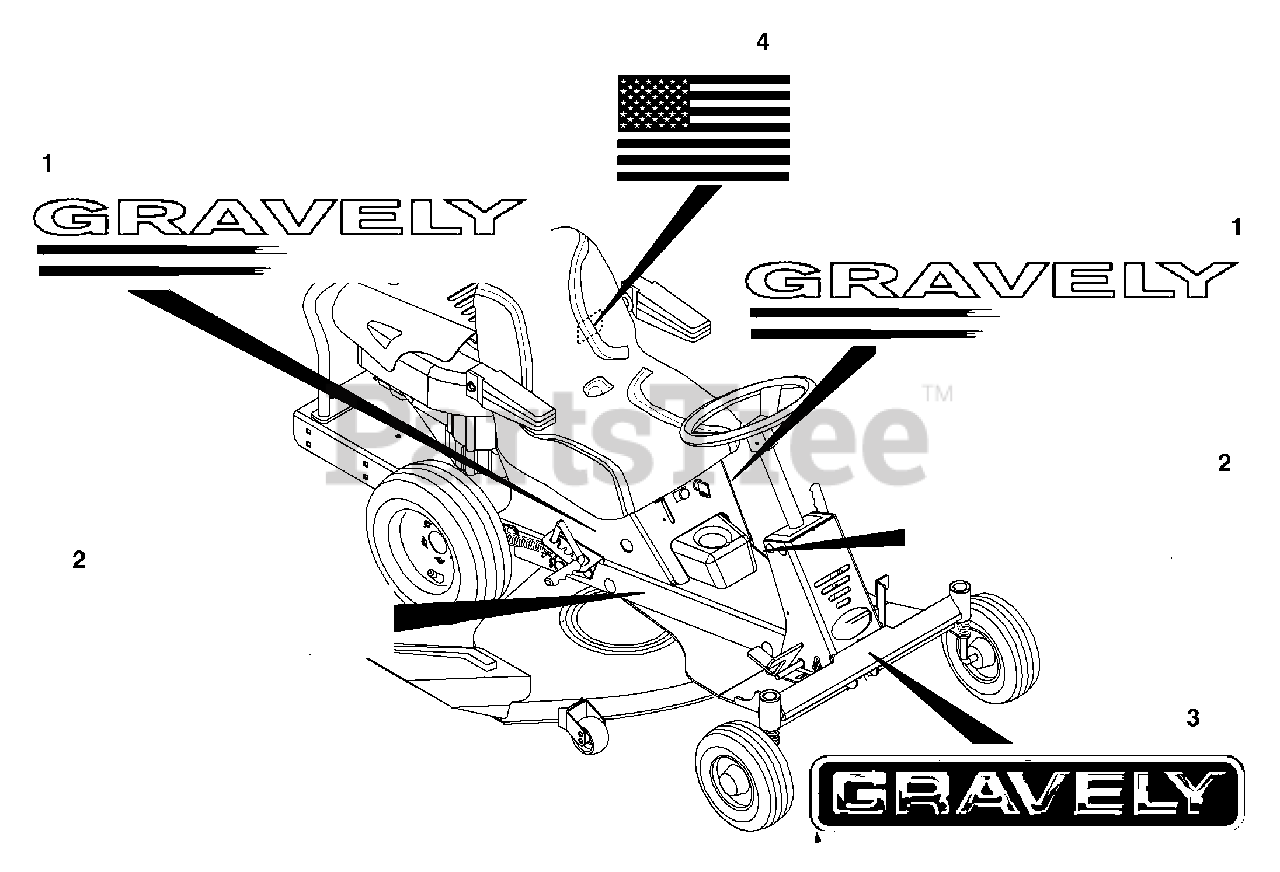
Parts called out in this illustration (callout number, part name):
1	Decal, Gravely ZT
2	Decal, Rear Engine Rider Gravely 1232 (062)
2	Decal, Rear Engine Rider Gravely 1028 (060)
2	Decal, Rear Engine Rider Gravely 1440 (064)
3	Decal, Gravely
4	Decal, American Flag
